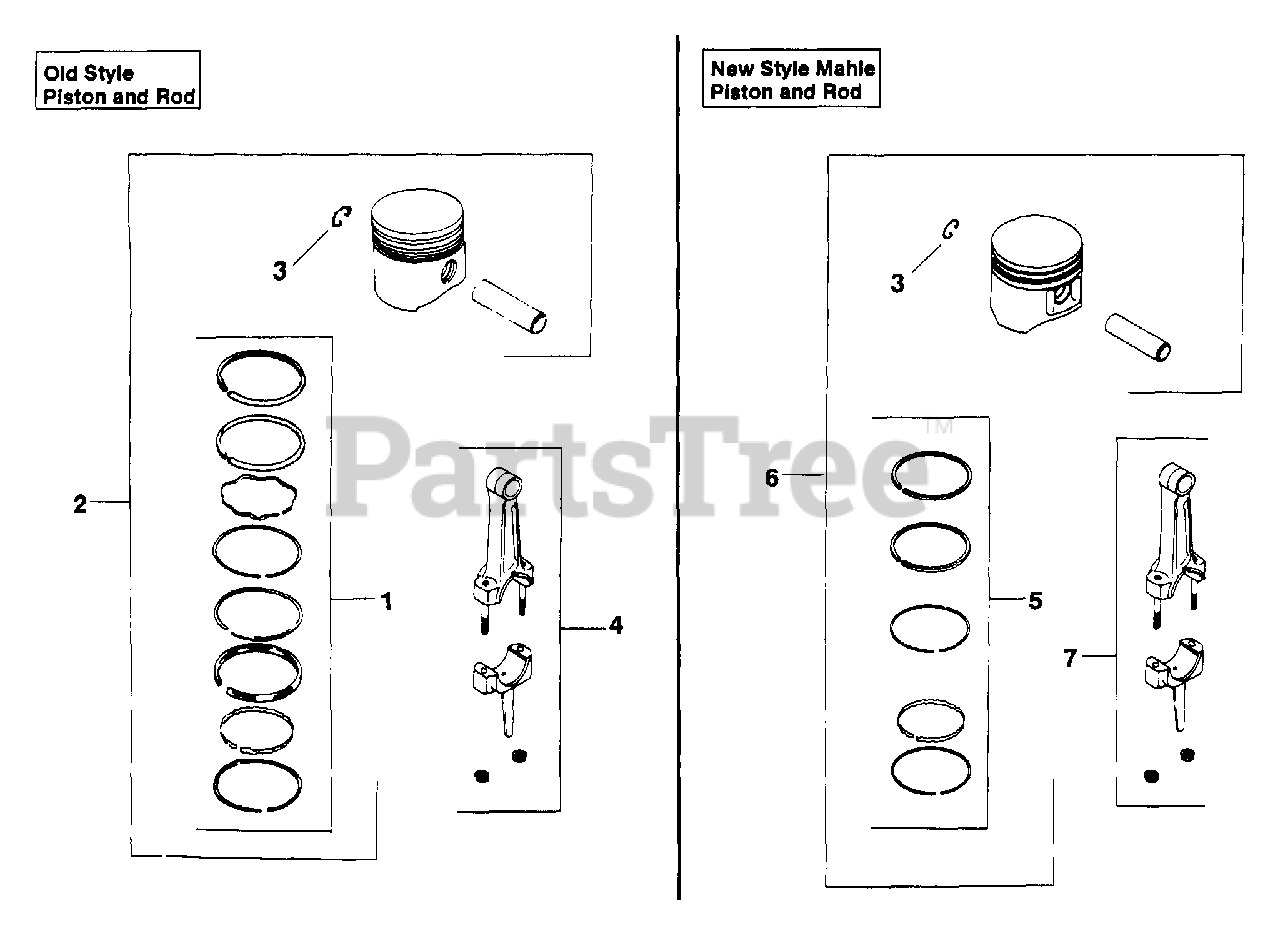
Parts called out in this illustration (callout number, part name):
3	RING, RETAINING
5	RINGS STD.
5	RINGS .010
5	RINGS .020
5	RINGS .030
6	KIT, PISTON W/RING SET STD
6	PISTON W/RING SET .003 - DISCONTINUED
6	PISTON W/RING SET .010
6	KIT, PISTON W/RING SET .020 - DISC.
6	PISTON W/RING SET .030
